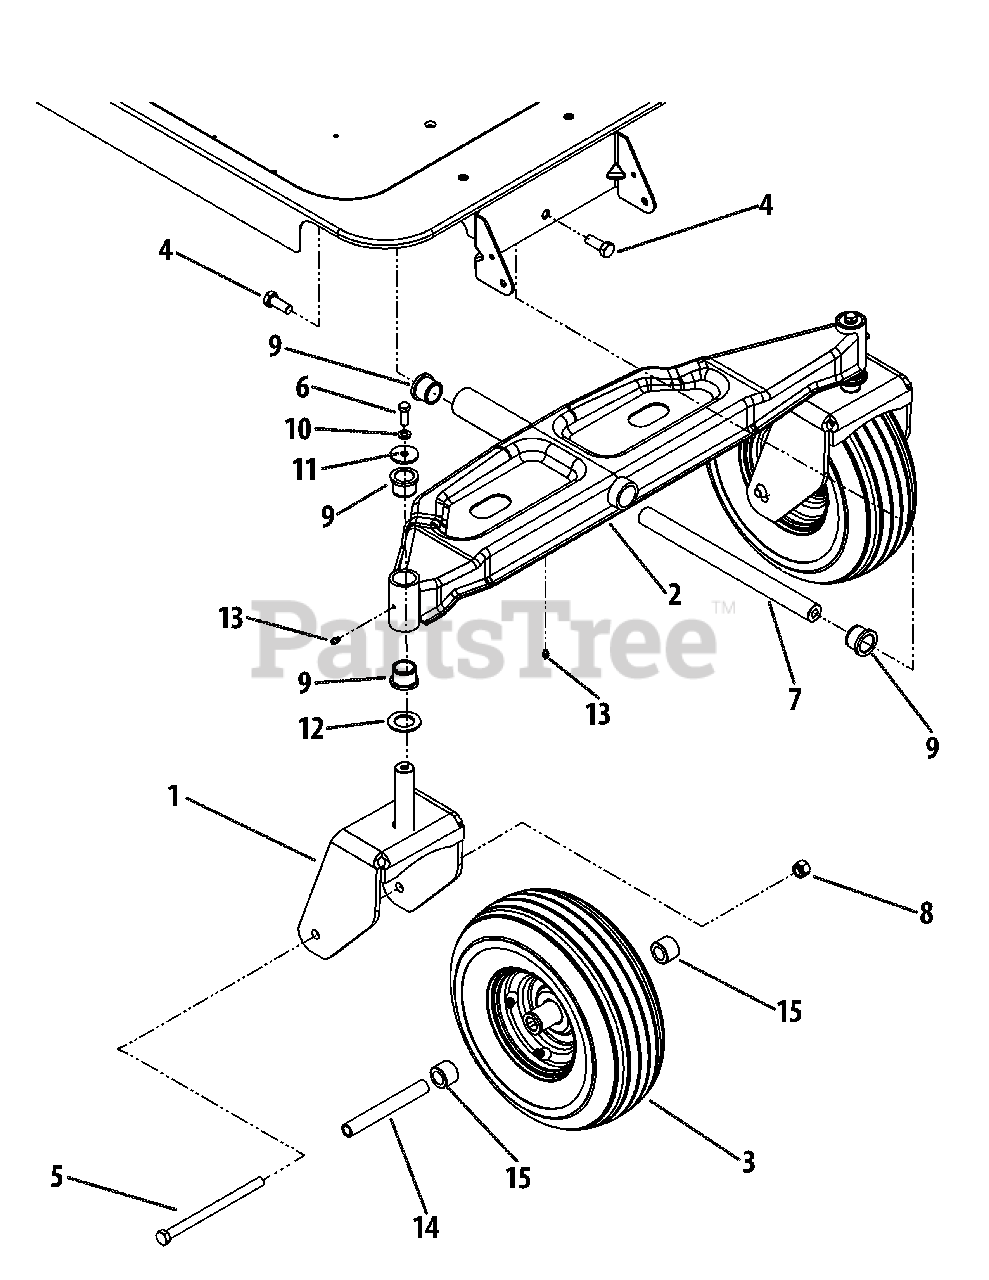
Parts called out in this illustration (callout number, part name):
1	Castor Wheel Bracket
2	Front Pivot Axle
3	Wheel Assembly, 13 x 5-6
4	Hex Lock Screw, 1/2-13 x 1.25
5	Hex Cap Screw, 1/2-20 x 7.25
6	Hex Cap Screw, 3/8-16 x 1.0
7	Axle Shaft
8	Hex Insert Lock Nut, 1/2-13
9	Flange Bearing, 1.0 x 1.246
10	Lock Washer, 3/8
11	Flat Washer, .39 x 1.5 x .134
12	Flat Washer, 1.0 x 1.75 x .10
13	Lube Fitting, 3/16 Drive
14	Spacer, .51 x .75 x 5.825
15	Hub, .76 x 1.23 x .92
